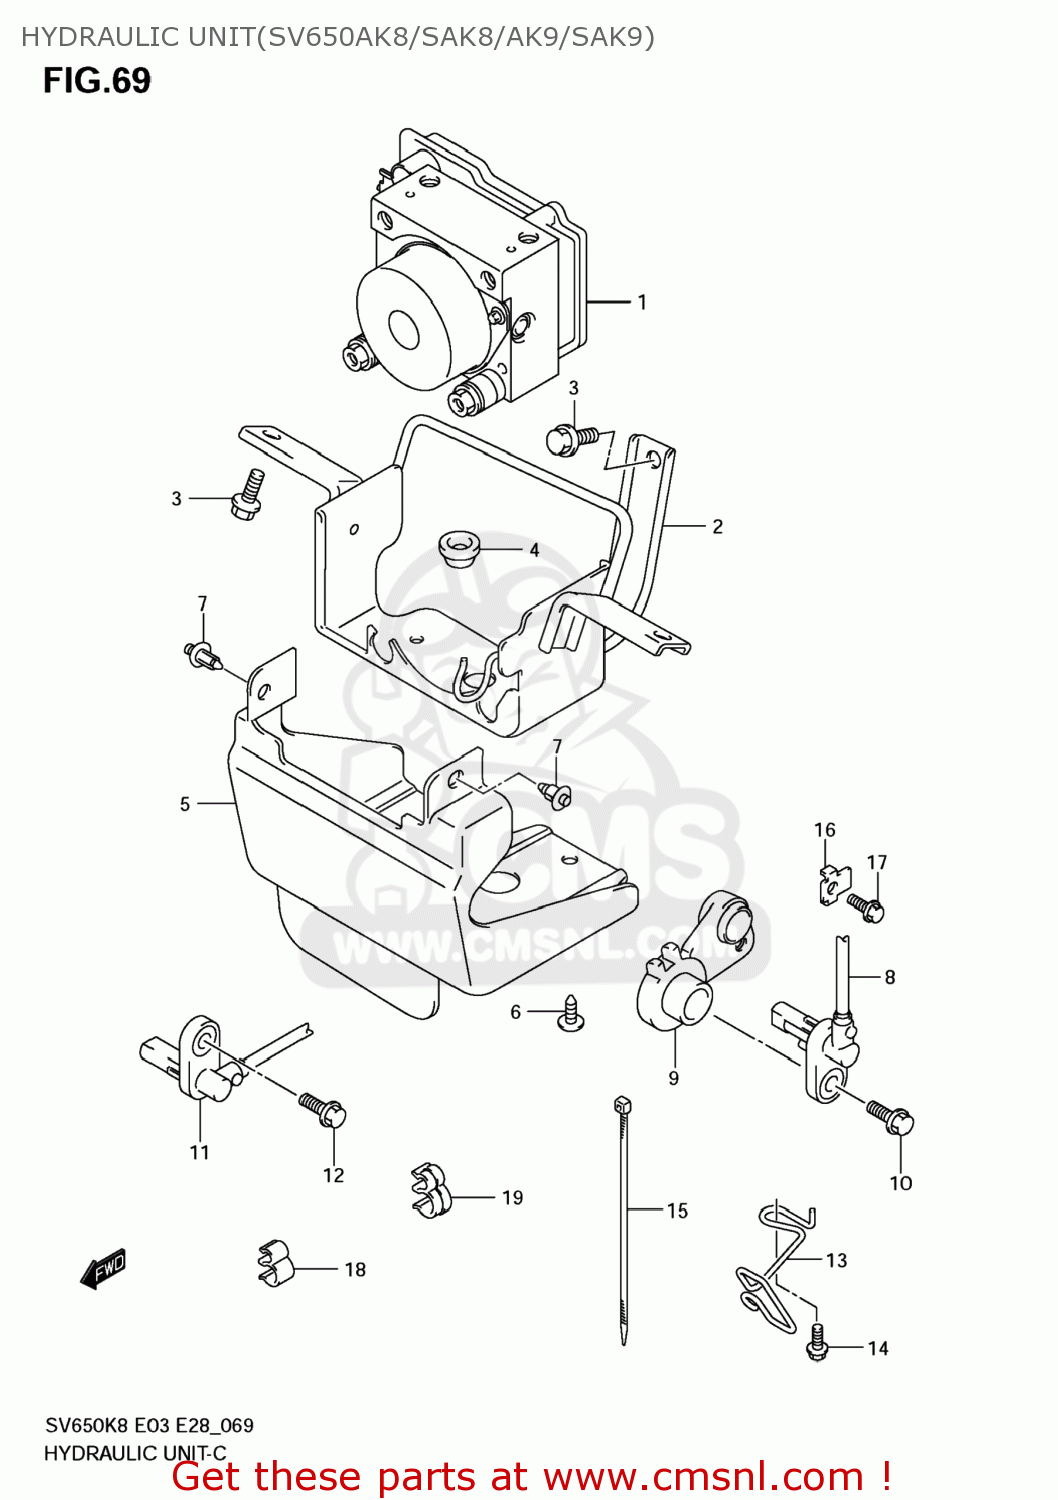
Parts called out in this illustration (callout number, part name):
1	UNIT ASSY,HYDRAULIC ABS
2	HOLDER,HYDRAULIC UNIT ABS
3	BOLT
4	DAMPER,ACTUATOR MOUNT
5	COVER,HYDR ABS UNIT
6	BOLT(6X16)
7	CLIP
8	SENSOR,FR WHEEL ABS
9	BRACKET,SPEED SENSOR FR
10	BOLT
11	SENSOR,RR WHEEL ABS
12	BOLT
13	GUIDE,SENSOR
14	BOLT
15	CLAMP(L:145)
16	GUIDE,SENSOR LEAD
17	BOLT
18	CLAMP
19	CLAMP
